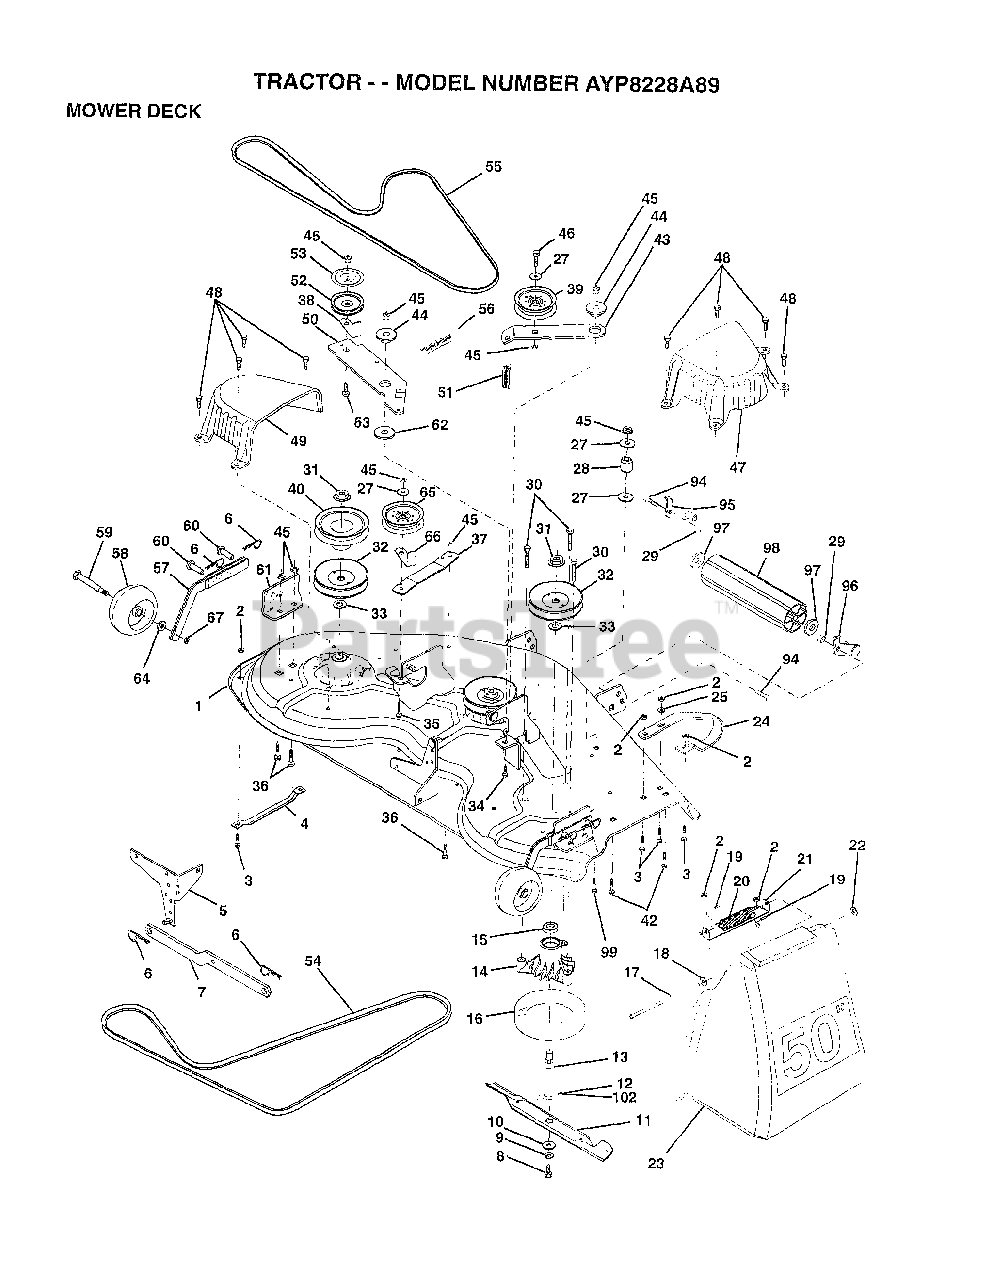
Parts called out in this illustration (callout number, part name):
1	"DECK ASM-50"""
4	RUNNER-LH M
5	BRKT.ASM.SW.44/50
8	BLADE BOLT
10	WASHER.HARD.BLADE
11	"BLADE.50"" HD"
12	BEARING.BALL
13	SHAFT.ASM.W/BRNG
14	HOUSING.MAND.44.V
15	BEARING
16	STRIPPER RND MWR
17	ROD-HINGE T
18	WASHER
19	CAP-SLEEVE LT
20	SPRING TORSION
21	BRKT DEFLECTOR
22	NUT PUSH M
23	DEFLECTOR
24	"RUNNER RH 50"" DK"
25	WASHER M
27	WASHER
29	NUT
30	"SCREW-THD ROLL,WA"
32	PULLEY.MANDREL.42
33	WASHER
34	BOLT.3/8-14X1.25
35	BOLT
36	BOLT D
37	STIFFENER.ARM.IDL
38	"KEEPER-BELT,IDLER"
39	FLAT IDLER PULLEY
40	"PULLEY.DRIVEN.44"""
42	BOLT
43	"ARM.IDLER.SEC.44"""
44	SPACER RETAINER
47	"COVER.MAND.RH.44"""
48	SCREW.1/4-20X5/8
49	COVER.MANDREL.LH
50	ARM.IDLER.PRIMARY
51	"SPRING.SEC.44""VEN"
52	PULLEY.IDLER.VGRO
53	SHIELD.IDLER.44.V
54	BELT V PRIM 50
55	BELT-V.SEC.46.KEL
56	SPRING.EXT.DECK.
57	BAR.ASM.GUAGE.WHL
58	WHEEL GAGE DONUT
59	BOLT.SHOULDER
60	PIN.CLEVIS
61	BRACKET.GUAGE.WHL
62	HARDENED WASHER
63	BOLT.3/8-16X1.50
64	WASHER
65	PULLEY IDELR FLAT
66	"KEEPER-BELT,IDLER"
67	LOCKNUT
94	BOLT
97	WASHER
99	BOLT
102	WASHER.FELT.
